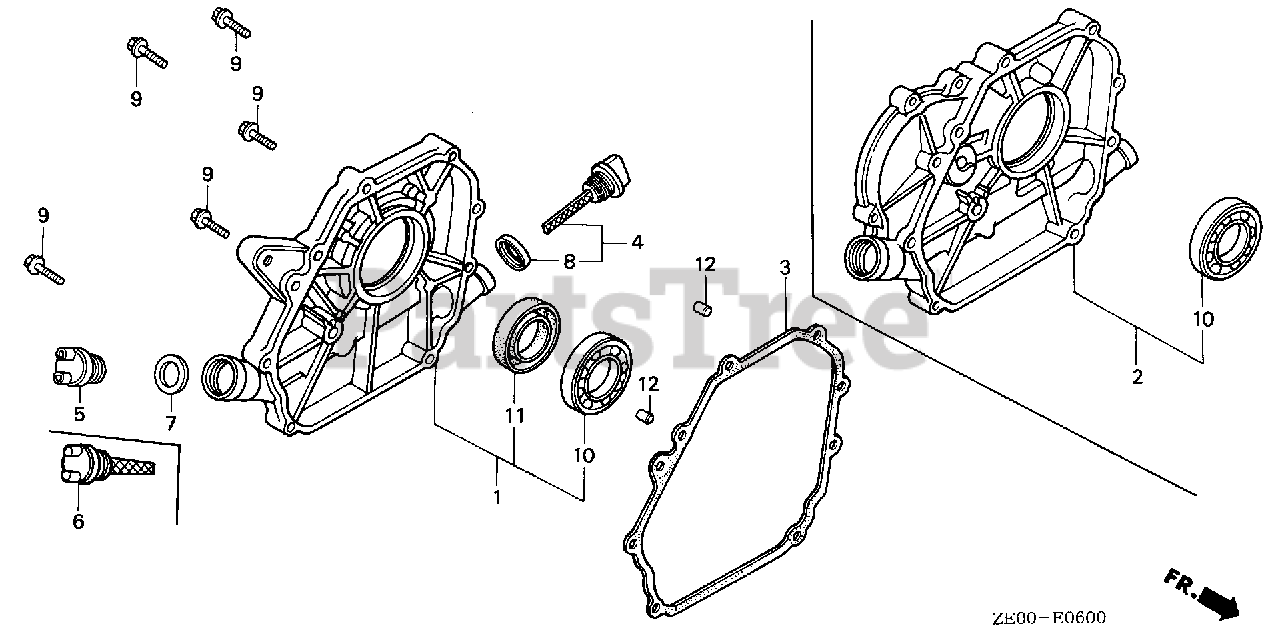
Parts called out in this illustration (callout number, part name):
1	COVER ASSY., CRANKCASE
3	GASKET, CASE COVER
4	CAP ASSY., OIL FILLER (GRAY)
5	CAP, OIL FILLER
6	CAP, OIL HOLE
7	GASKET, OIL FILLER CAP
8	GASKET, OIL FILLER CAP
9	BOLT, FLANGE (6X28) (CT200)
10	BEARING, RADIAL BALL
11	OIL SEAL (22X41X6)
12	PIN, DOWEL (8X14)
